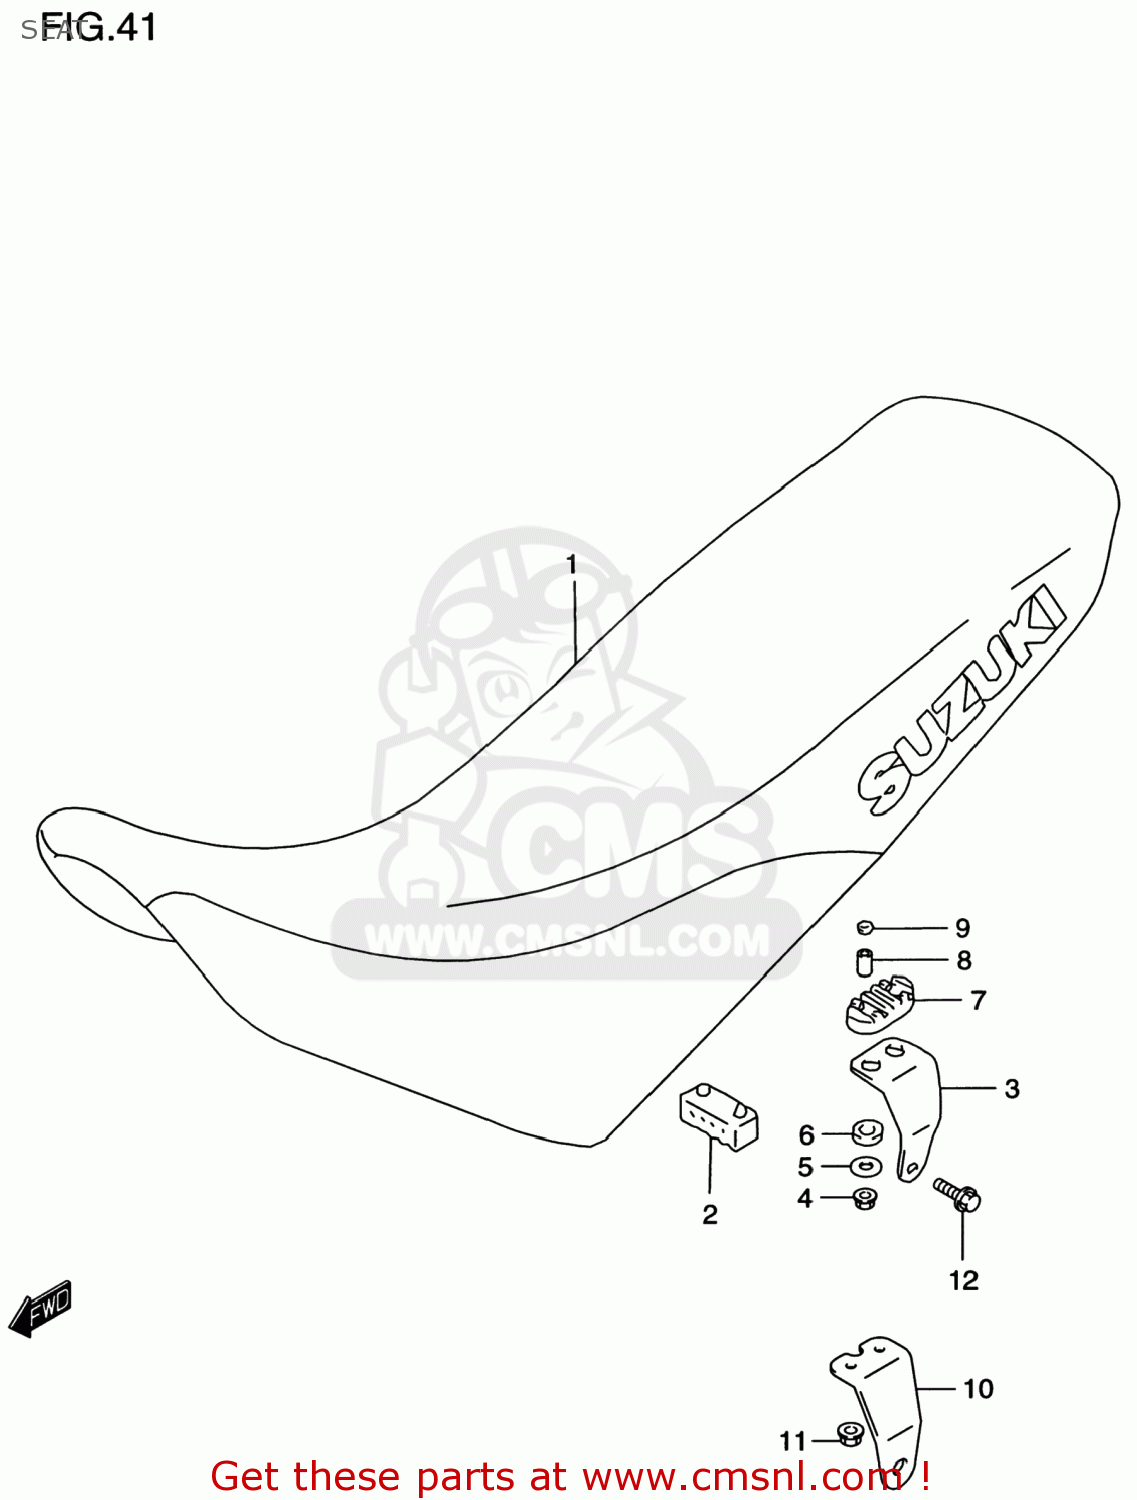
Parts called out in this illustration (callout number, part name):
1	SEAT SET
2	CUSHION,SEAT(40X20X15)
3	BRACKET,SEAT
4	NUT
5	WASHER(6.5X20X1.6)
6	CUSHION,SEAT
7	CUSHION,SEAT
8	SPACER,SEAT
9	WASHER
10	BRACKET
11	NUT
12	BOLT
